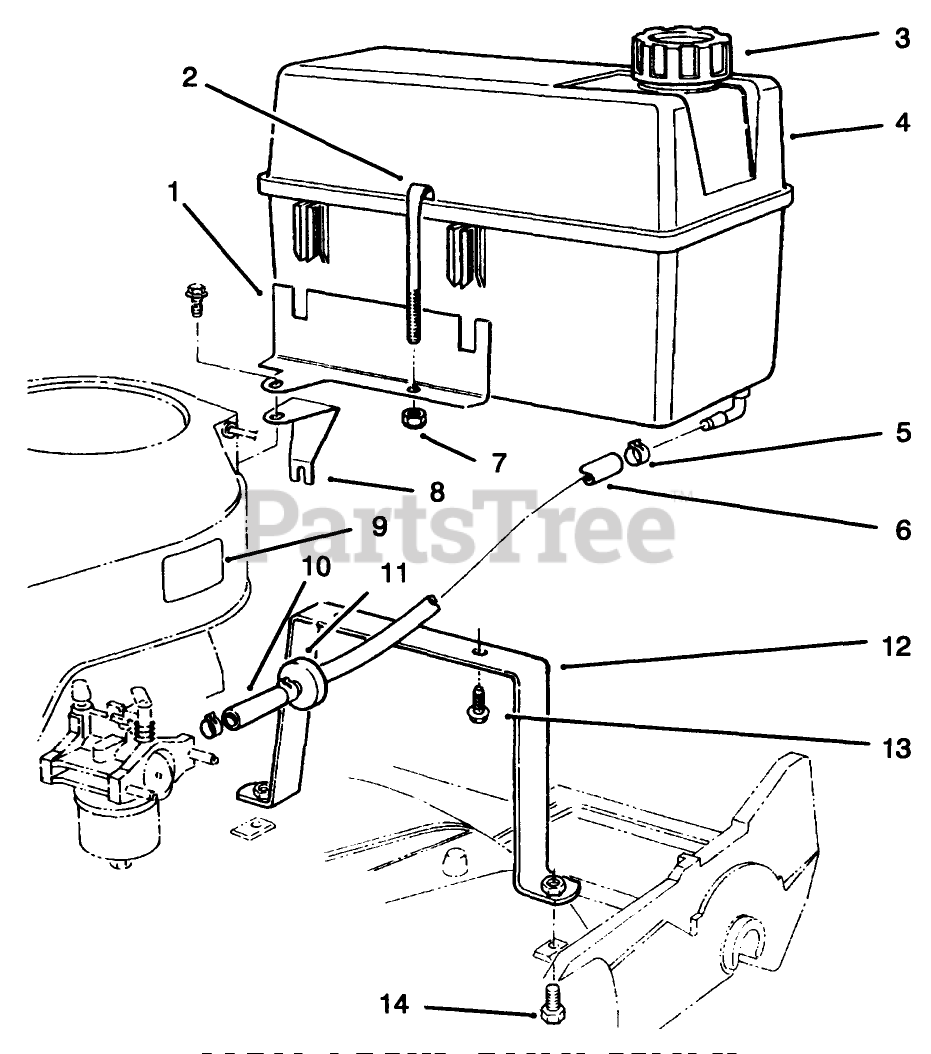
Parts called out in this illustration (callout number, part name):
2	RETAINER - FUEL TANK
3	GAS CAP ASM
5	CLAMP-FUEL LINE
6	HOSE-FUEL
7	NUT-LOCK, NI
9	DECAL - FUEL
10	HOSE-FUEL
11	FILTER-FUEL
13	SCREW-HWH
14	SCREW-HH
